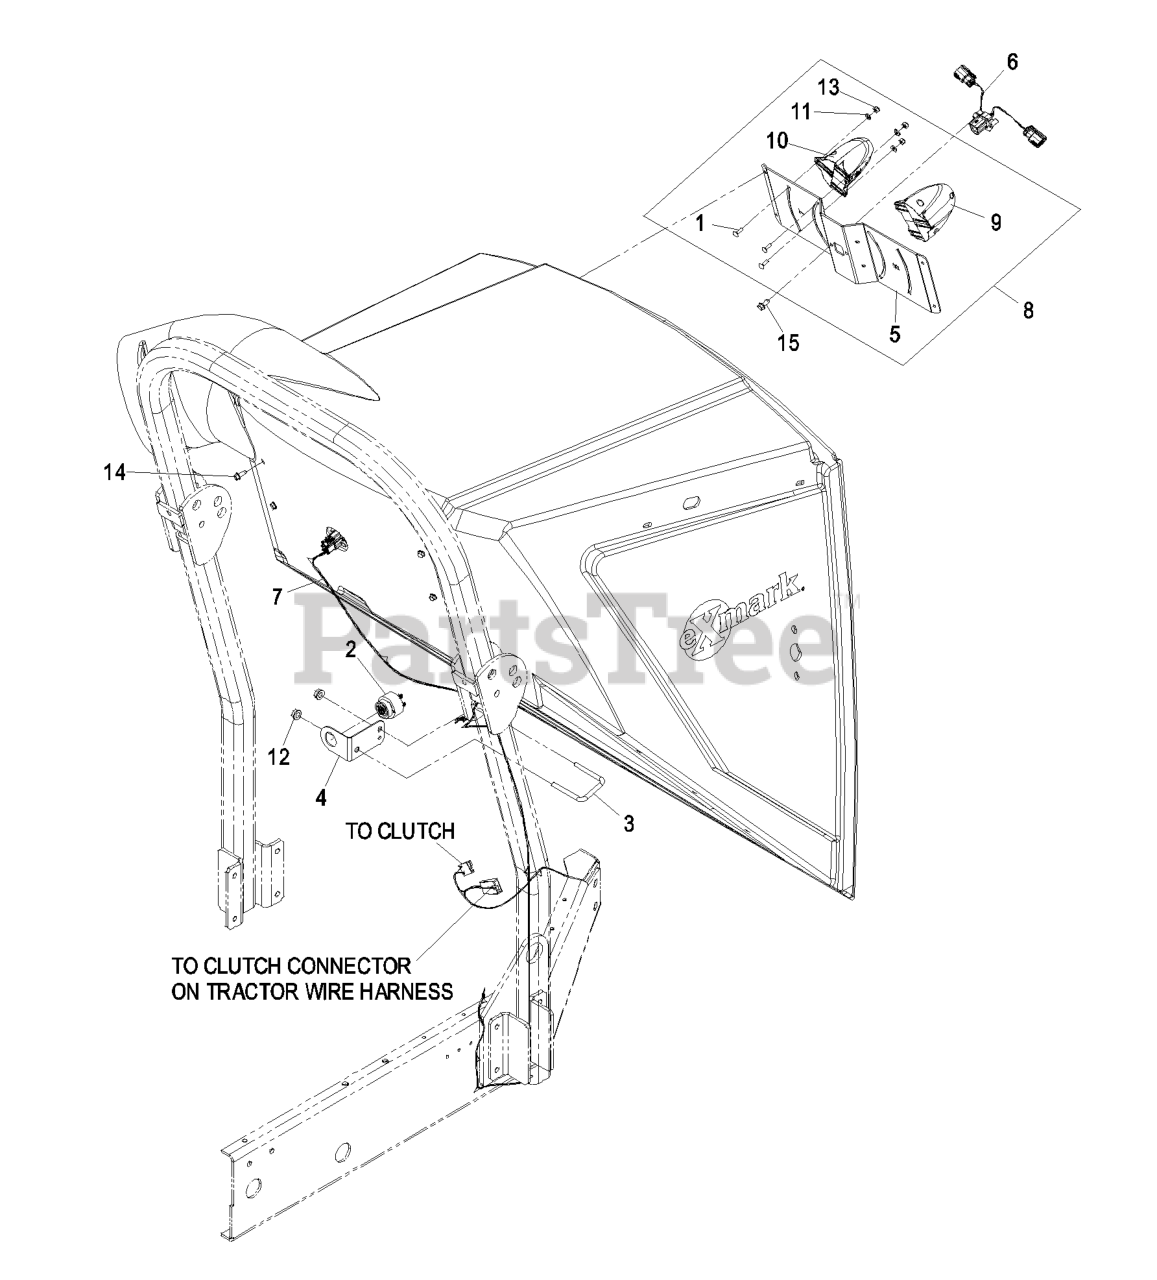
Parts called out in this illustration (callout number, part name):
1	BOLT-CARR
2	ALARM-TONE, DUAL
4	BRACKET,FRUVD ALARM MTG
5	PLATE,FILL SENSOR MTG
6	HARNESS,FRUVD HOPPER
7	HARNESS,FRUVD TRACTOR
8	Asm, Sensor Plate
9	BAG SENSOR ASM
10	BAG SENSOR ASM
11	WASHER-FLAT
12	NUT-HHF, WHIZ
13	NUT-LOCK, NI
14	SCREW-HWH
15	SCREW-PPH
